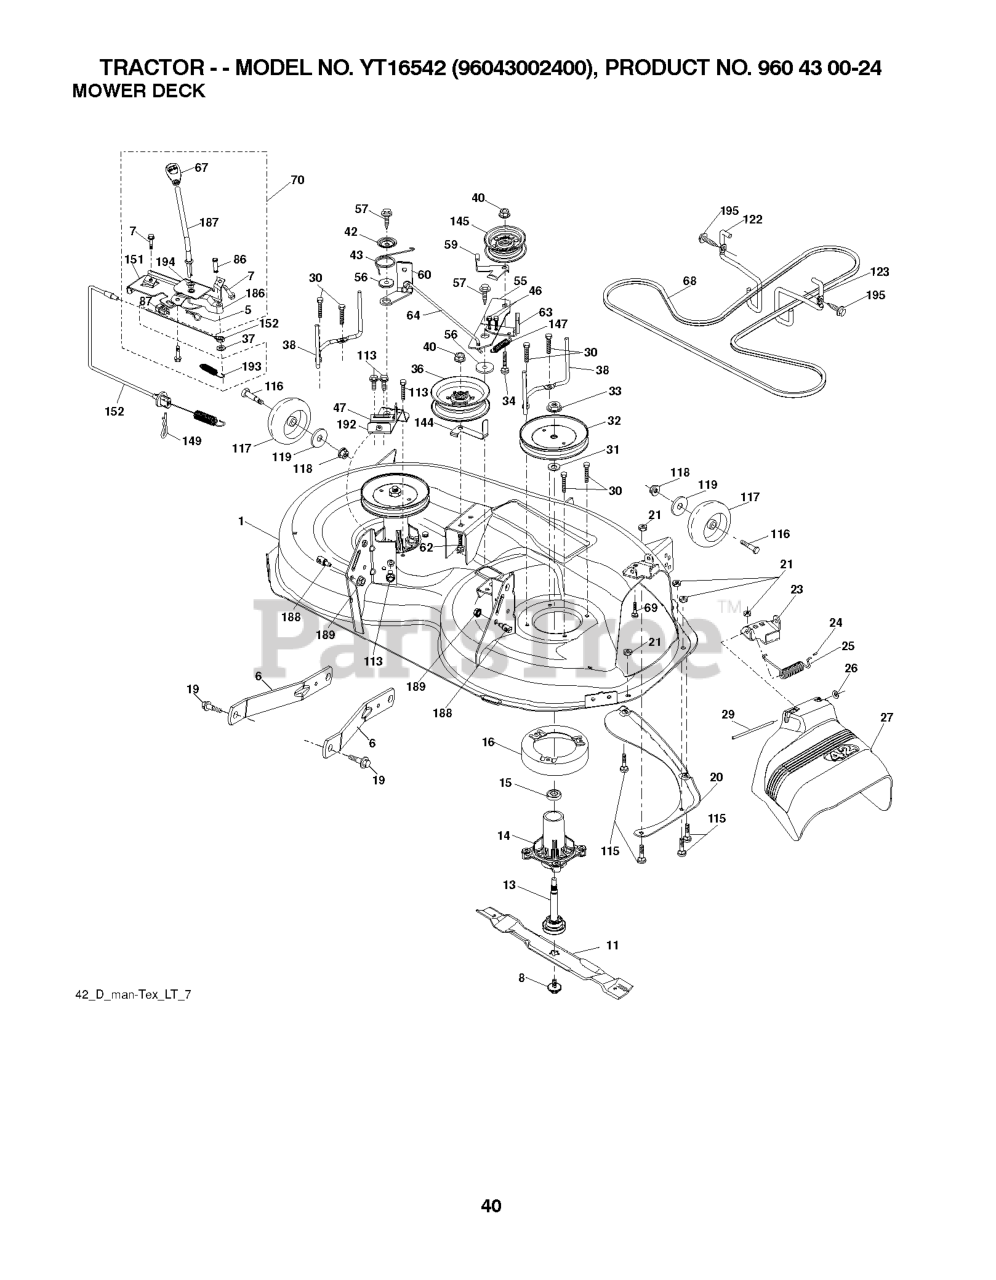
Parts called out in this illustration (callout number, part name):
1	DECK.WELDMENT.42"
5	RETAINER-SPRNG RB
6	ARM.SUSPENSION.MOWER.R
7	SCREW
8	BOLT.WASHER.ASM.7/16-2
11	42" HI-LIFT BLADE
13	SHAFT.ASM.MDRL.N/GREASE.38
14	RP.HOUSING.MANDREL.4PT.
16	STRIPPER.MANDREL.ROUND.BLACK
19	BOLT.SHOULDER
20	BAFFLE.VORTEX
21	LOCKNUT
23	BRKT.DEFLECTOR.38"2005+
24	CAP-SLEEVE LT
25	SPRING.TORSION.DEFLECT
26	NUT PUSH M
27	SHIELD.DEFLECTOR.MOWER.42"BLAC
29	ROD.HINGE
30	SCREW, WASHER HEAD
31	WASHER.SPACER.MANDREL
32	PULLEY.MANDREL.5.438.P
33	NUT.FLANGE.LOCK.TOP
34	BOLT.3/8-16X1.50
36	PULLEY.IDLER.2006
37	WASHER
38	KEEPER.BELT.LH.MANDREL
40	NUT LOCK FLG 3/8-16 UNC
42	SPRING.TORSION.BRAKE
43	SRPING.TORSION.RETAINE
46	SCREW.1/4-20X5/8
47	BRKT.CLUTCH.CABLE
55	IDLER.ARM
56	SPACER.RETAINER
57	SCREW 3/8-16X1
59	GUARD, BELT
60	ARM BRAKE MOWER
62	BOLT
63	ARM.BRAKE.ZINC
64	LINKAGE.BRAKE.ASM.ZINC
67	HANDLE.CLUTCH.CABLE.LT
68	BELT.DRIVE.MOWER.TEX.42"
69	BOLT
70	CLUTCH.ASM.MANUAL.LT.PRED
86	PIN ATTACHMENT CABLE
87	SWITCH.INTRLCK.CLUTCH.
113	BOLT.5/16HEX.WHS.HD
115	BOLT.CARR.5/16-18X5/8.SHORT
116	BOLT M
117	WHEEL.GAGE.HALF.SPOKED
118	LOCKNUT
119	WASHER.5/16.FLAT.STE.STD.
122	KEEPER BELT ENGINE LH
123	KEEPER BELT RH
144	KEEPER.BELT.MOWER
145	PULLEY.IDLER.FLAT
147	RETURN SPRING
149	SPRING.RETAINER.YELLOW.ZINC
151	BRACKET.CLUTCH CBL.PRED LT
152	CABLE.CLUTCH.MANUAL.W/
186	ARM ACTUATOR
187	LEVER.CONTROL.CL.CABLE.PRED LT
188	STUD.FASTNER.W/ANTI-ROTATE
189	NUT LOCK HEX FLANGE 5/16-18
192	BRKT.BRAKE.STAND.LH.
194	BEARING.CONTROL.LEVER.CLUTCH
195	SCREW, 3/8-16X3/4
197	SPRING.PLUNGER.ACTUATOR
